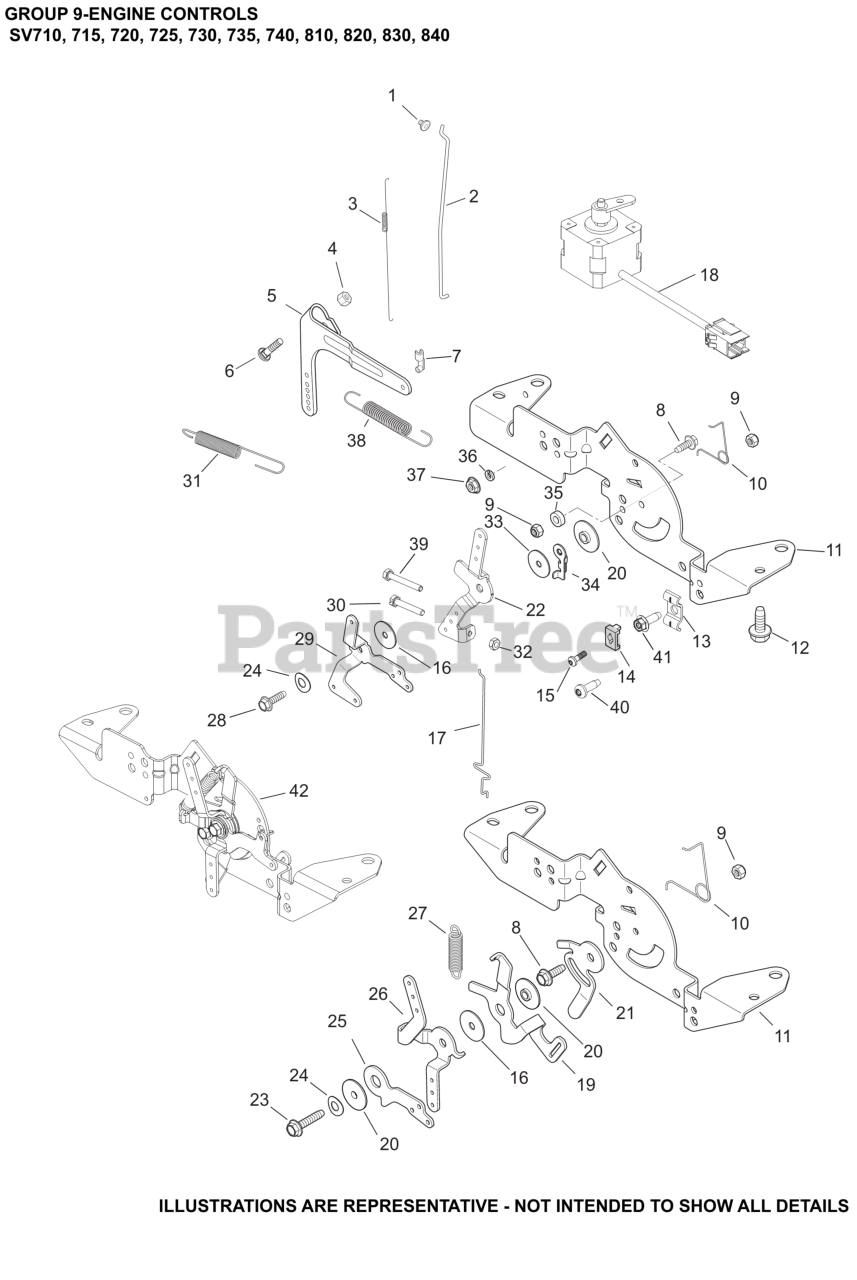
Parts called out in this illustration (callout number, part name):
1	BUSHING, LINKAGE RETAINING
2	LINKAGE, THROTTLE
3	SPRING, LINKAGE
4	NUT, FLG M6X1.0
5	LEVER, GOVERNOR - (#2409069S)
6	BOLT, RD HD SQ NECK M6X1.0X25
7	BUSHING, THROTTLE LINKAGE
9	SCREW, THREAD FORMING
9	NUT, LOCK M5X.8
10	SPRING, CHOKE RETURN
11	BRACKET, SPEED CONTROL
12	SCREW, THREAD FORMING
14	CLAMP, CABLE-(#2523753S)
16	WASHER, FLAT 5.5 MM
17	LINKAGE, CHOKE
19	LEVER, GOVERNOR SPRING
20	SPACER, CONTROL ASSEMBLY
21	LEVER, SPEED SETTING
23	SCREW, THREAD FORMING-USE 25 086 472-S
24	WASHER, SPRING 1/4"
25	LEVER, CHOKE - USE 32 536 12-S
26	LEVER, SPEED CONTROL-USE 32 090 26-S
27	SPRING, SPEED CONTROL
31	SPRING, GOVERNOR (PURPLE)
38	SPRING, GOVERNED IDLE
NI	SCREW, THREAD FORMING
